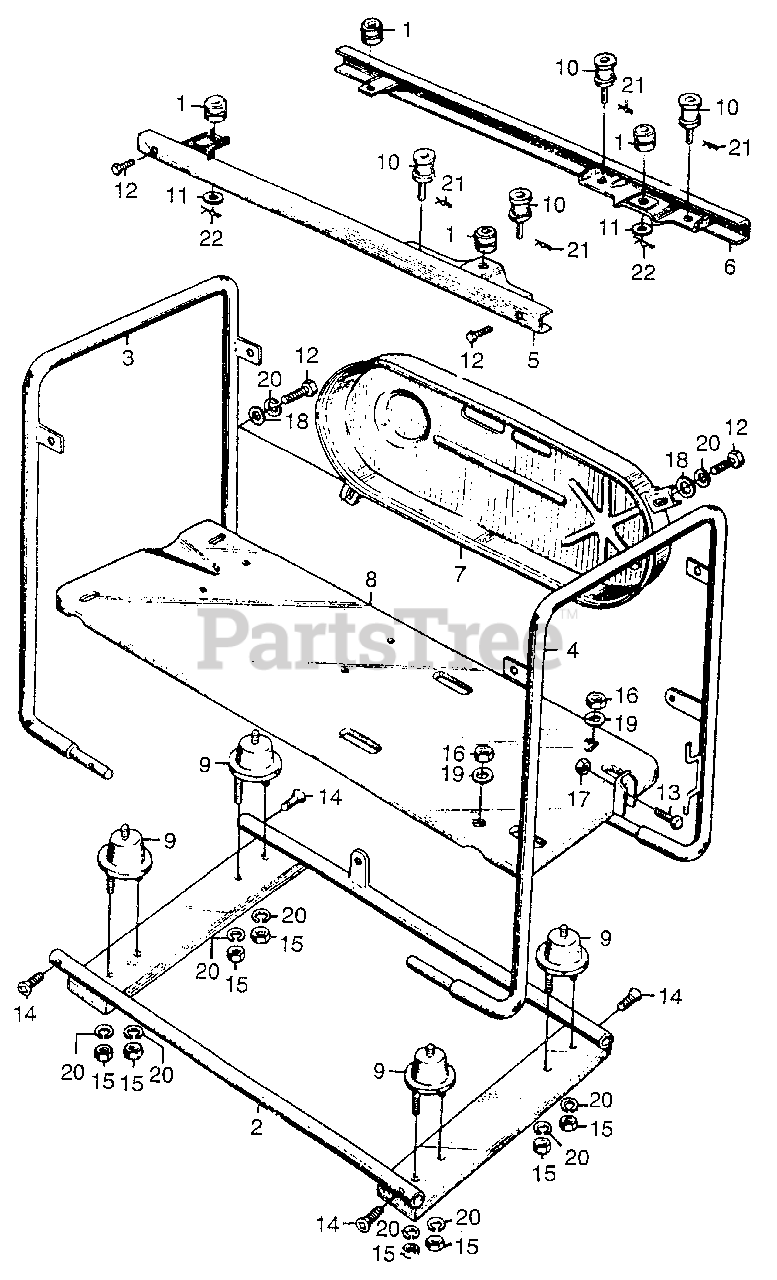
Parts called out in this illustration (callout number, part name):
1	RUBBER, TANK CUSHION
2	BED, FRAME
5	FRAME, FR.
6	FRAME, RR.
7	COVER, BELT *R2* (SCARLET)
8	BED, ENGINE
9	RUBBER, ENGINE SETTING
10	RUBBER, CONTROL BOX SETTING (NOT AVAILABLE)
11	WASHER, FLAT (20MM)
12	BOLT, HEX. (6X12)
13	BOLT, HEX. (8X35)
14	SCREW, OVAL (8X14) (NOT AVAILABLE)
15	NUT, HEX. (6MM)
16	NUT, HEX. (8MM)
17	NUT, HEX. (8MM)
18	WASHER, PLAIN (6MM)
19	WASHER, PLAIN (8MM)
20	WASHER, SPRING (6MM)
21	PIN, LOCK (5MM)
22	PIN, LOCK (6MM)
